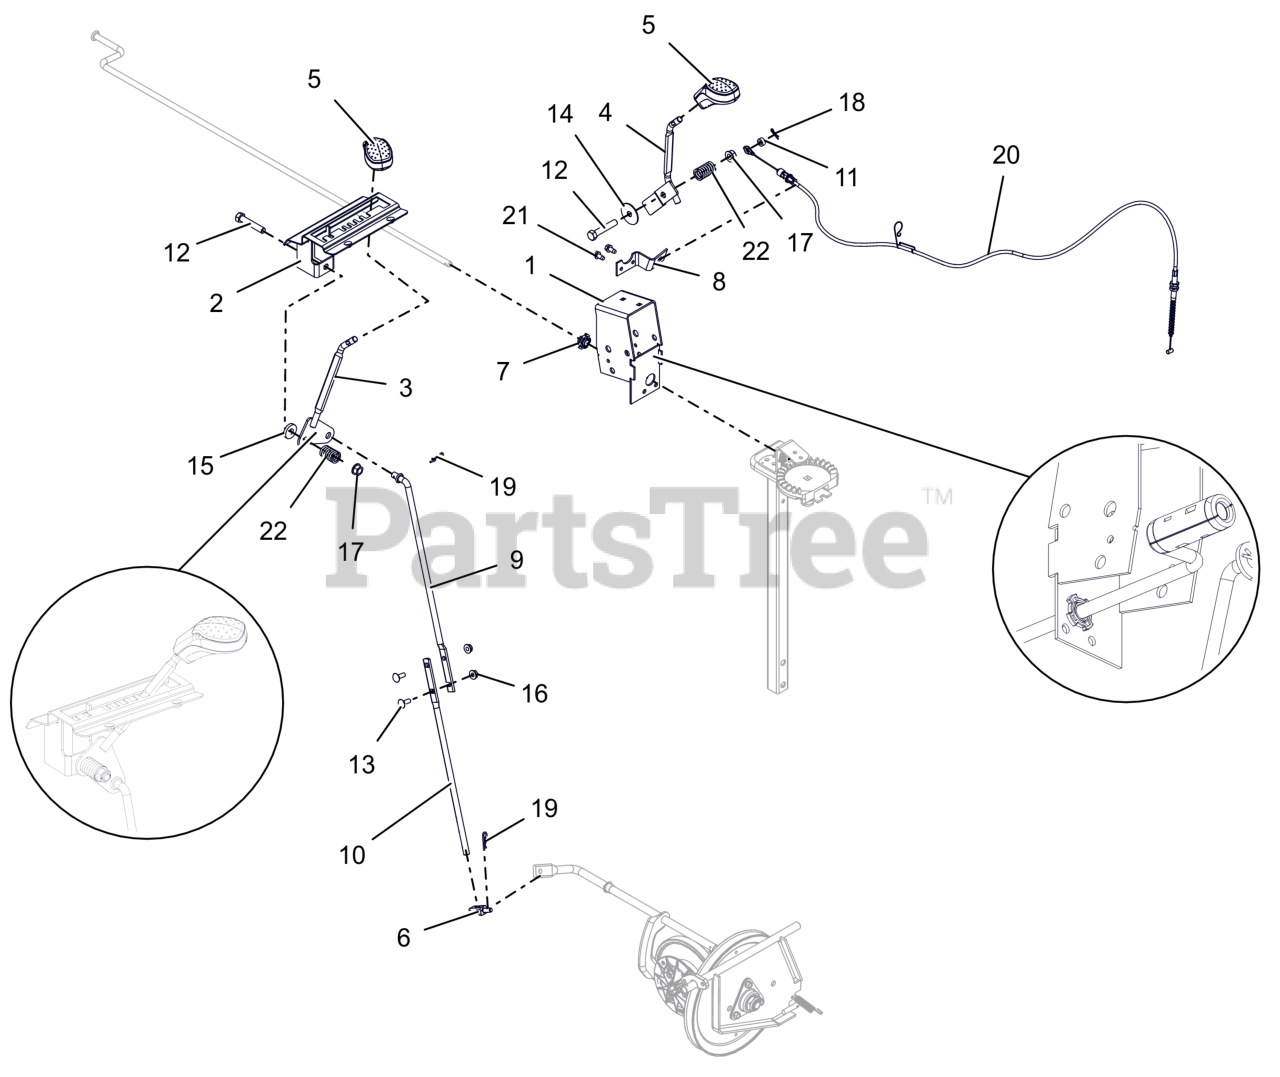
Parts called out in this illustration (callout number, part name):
1	WELDMENT, BRACKET INTERLOCK
2	WELDMENT, DETENT PLATE-COMPACT
3	LEVER, CONTROL-SHIFT(WELDMENT)
4	WELDMENT,SM DASH DEFL CONTROL
5	KNOB, CONTROL, DASH
6	PIVOT,SHIFT ROD .375-16(TRUNN)
7	CRANK BUSHING, NYLON CHUTE BK
8	ANCHOR, DEFLECTOR CABLE
9	ROD, SHIFT UPPER
10	ROD, SHIFT - LOWER
11	BSHG-SLV .265X.500X.219
12	BLT,HEX .38-16X2.00 G5 ZCC
13	BLT, RHSN .25-20X.750 G5 ZCC
14	WSHR,FLT .380X1.50X.062 ZCC
15	WSHR, FLT .406X1.00X.188 ZCC
16	NUT-LK-CTR-FLG .25-20 ZC120
17	NUT-LK-TOP-FLG .38-16 ZC120
18	PIN, HAIR #178 .06X.77 ZCC
19	PIN, HAIR #213 .08X1.19 ZCC
20	CABLE, DEFLECTOR - COMPACT
21	SCR-TAP .25-20X.50 HWH ZCC
22	SG-COMP .125X.781X1.250
